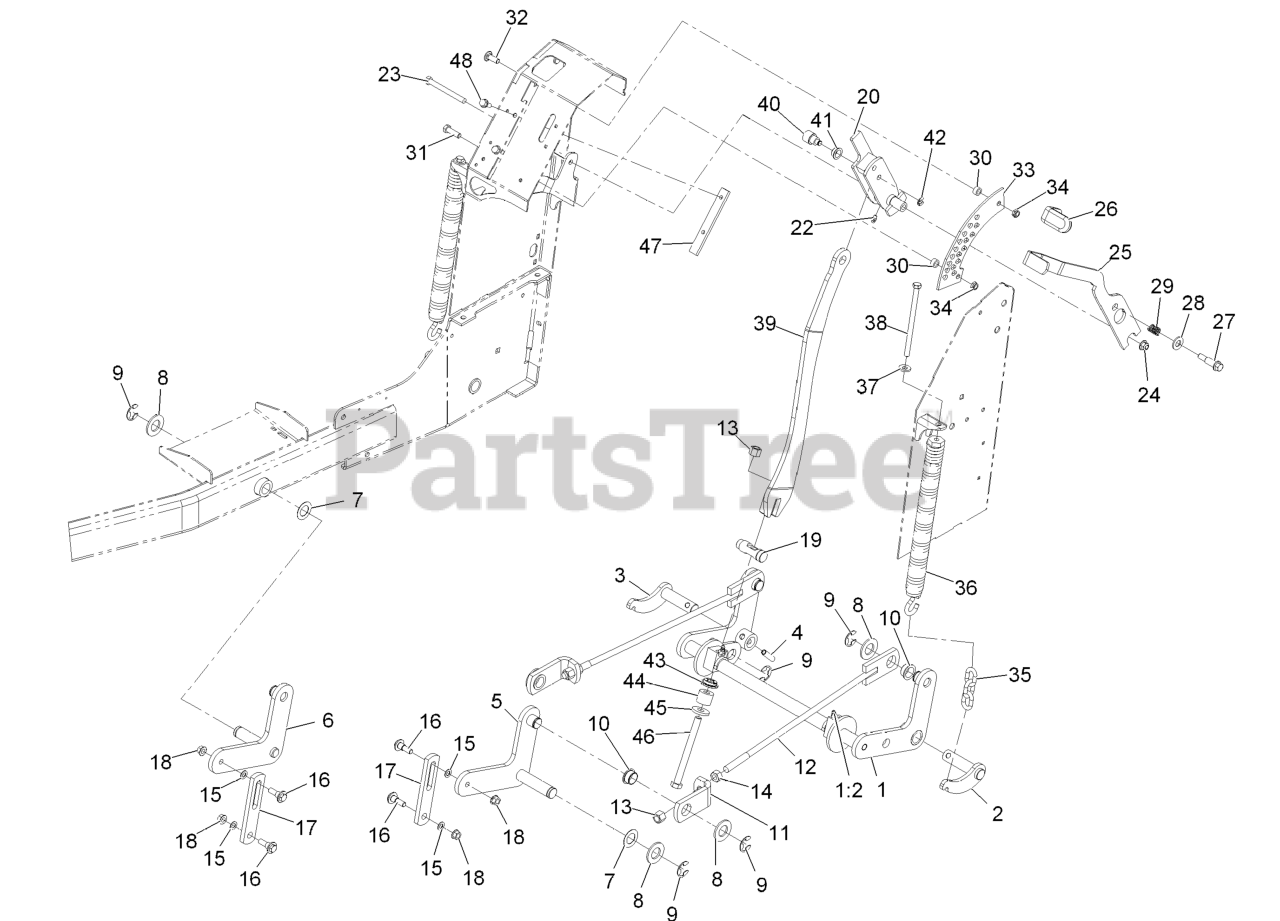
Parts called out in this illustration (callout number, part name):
1	REAR CROSSSHAFT ASM
1:2	FITTING-LUBE, 45 DEG
2	SHAFT-PIVOT, LH
3	SHAFT-PIVOT, RH
4	PIN-SPIRAL
7	WASHER-THRUST
8	WASHER-FLAT
9	RING-RETAINING, EXT
10	BEARING-FLANGE
11	BRACKET-LIFT ROD
12	LIFT ROD ASM
13	NUT-LOCK, NI
14	NUT-HH
16	SCREW-SHOULDER, HHF
17	LINK-LIFT
19	PIN-HOC
20	HOC HANDLE ASM
22	FITTING-GREASE
23	SCREW-HH
24	NUT-HF, NI
25	LEVER-HOC
26	GRIP-LEVER
27	SCREW-SHOULDER
28	WASHER-FLAT
30	SPACER
31	SCREW-HH
32	SCREW-CARR
33	BRACKET-HOC
35	CHAIN-DECKLIFT
36	SPRING-EXTENSION
37	WASHER-BELLEVILLE
38	BOLT-TAP, HH
39	BAR-LIFT
40	HUB-PIVOT
41	BEARING-FLANGE
42	RING-RETAINING
43	SEAT-SPRING
44	SPRING-URETHANE
46	SCREW-HH
47	SKID-HANDLE, LIFT
48	SCREW-THD ROLL, HWH
